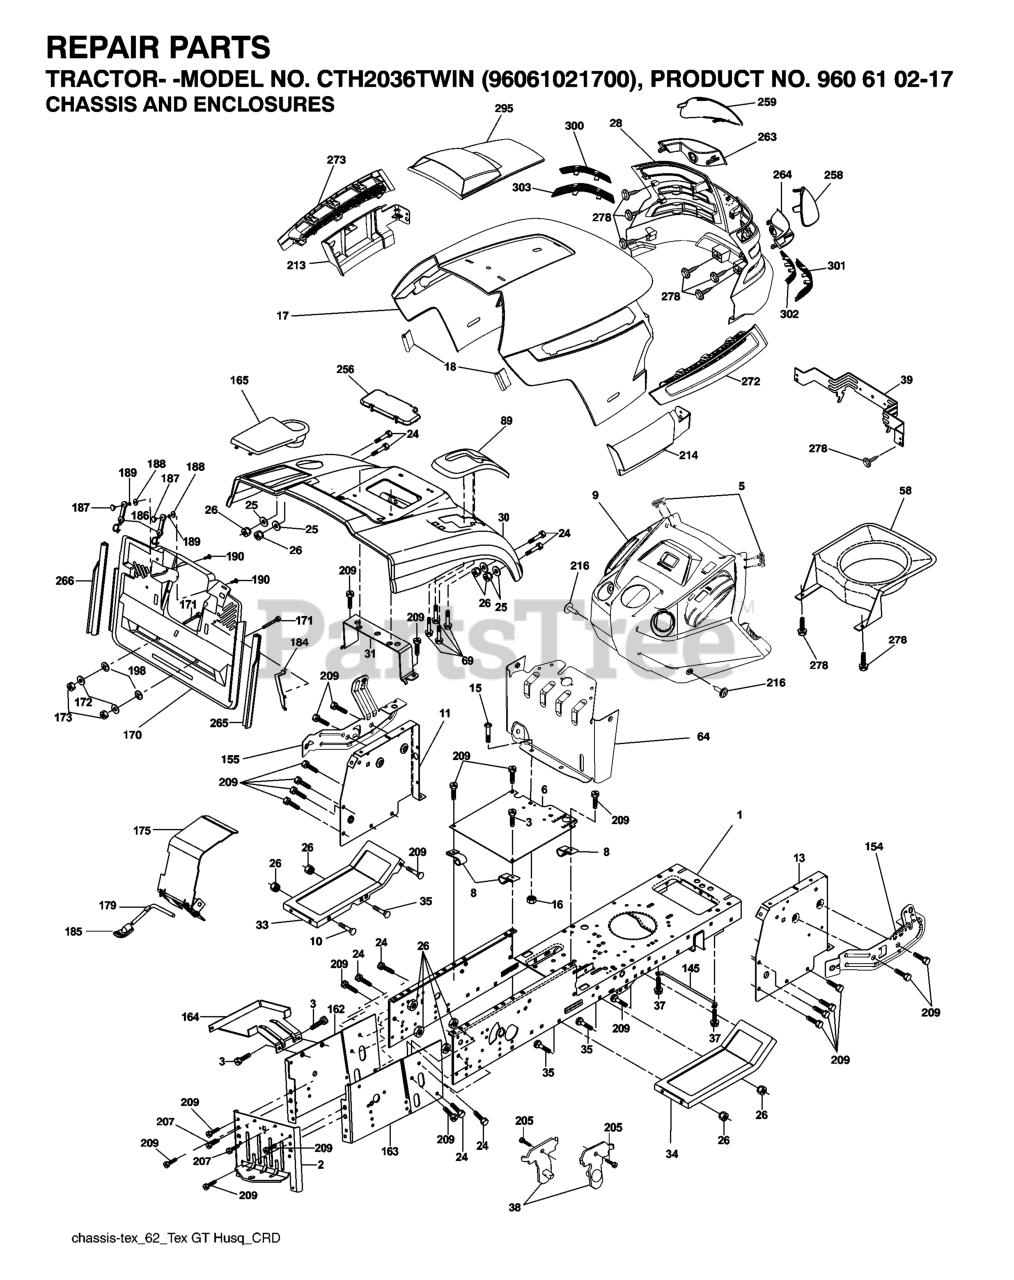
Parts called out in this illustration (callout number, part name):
2	DRAWBAR
3	SCREW 3/8-16X3/4
5	BUMPER DASH
6	PLATE
8	CLIP,INSULATOR
10	BOLT D
11	PANEL DASH LH
13	PANEL DASH RH
15	Screw, Machine, Truss Head 5/16-18 UNC x 3/4
16	NUT
17	HOOD
18	BUMPER.HOOD.TEX.HUSQVARNA
25	WASHER
26	NUT
28	GRILL.ASM.HUSQ.TG/CRD.W/TRIM
30	CONSOLE.CRD.AUTO.GRY
31	BRACKET SUPPORT FENDER
33	FOOTREST PNT LH
34	FOOTREST PNT RH
37	Screw 5/16-18 x 1/2 Hex, Self Tapping 5/16-18 x 1/2
38	BRACKET ASM PIVOT MOWER REAR
39	HOOD PIVOT BRACKET
58	AIR.DUCT.HOOD.TEX.GT.HUSQ
69	SCREW.HI-LO.CONSOLE
89	CONSOLE.CRD.AUTO.GREY.2005
145	ROD PIVOT CHASSIS/HOOD
162	BRACKET
163	BRACKET EXTEN CHASSIS RH CRD
165	RP.COVER.BATTERY.CRD.GREY
172	WASHER
175	DOOR TRAP
179	ROD PIVOT FBI
184	BRACKET.ACTUATOR.BAGGER.SRD
186	LATCH ASSY
187	WELDNUT
189	LOCKWASHER #10
190	SCREW
207	SCREW, 5/16-18 X 1/2
209	SCREW, 3/8-16X3/4
213	SKIRT.HOOD.SIDE.HUSQ.LH.GREY
214	SKIRT.HOOD.SIDE.HUSQ.RH.GREY
216	SCREW 14-20 X 5/8
256	COVER FENDER CRD
258	LENS.RH.TEX.GT.HUSQ.CL
259	LENS.LH.TEX.GT.HUSQ.CL
263	BEZEL.RH.TEX.GT.HUSQ
264	BEZEL.LH.TEX.GT.HUSQ
265	SEALING
266	SEALING
272	VENT.SIDE.HOOD.HUSQ.RH.GREY
273	VENT.SIDE.HOOD.HUSQ.LH.GRAY
278	SCREW
295	VENT.ASM.HOOD.TOP.TEX.
300	INSERT.HEX.GRILL.HUSQ.
301	INSERT.HEX.GRILL.HUSQ.GREY
302	INSERT.HEX.GRILL.HUSQ.
303	INSERT.HEX.GRILL.HUSQ.
